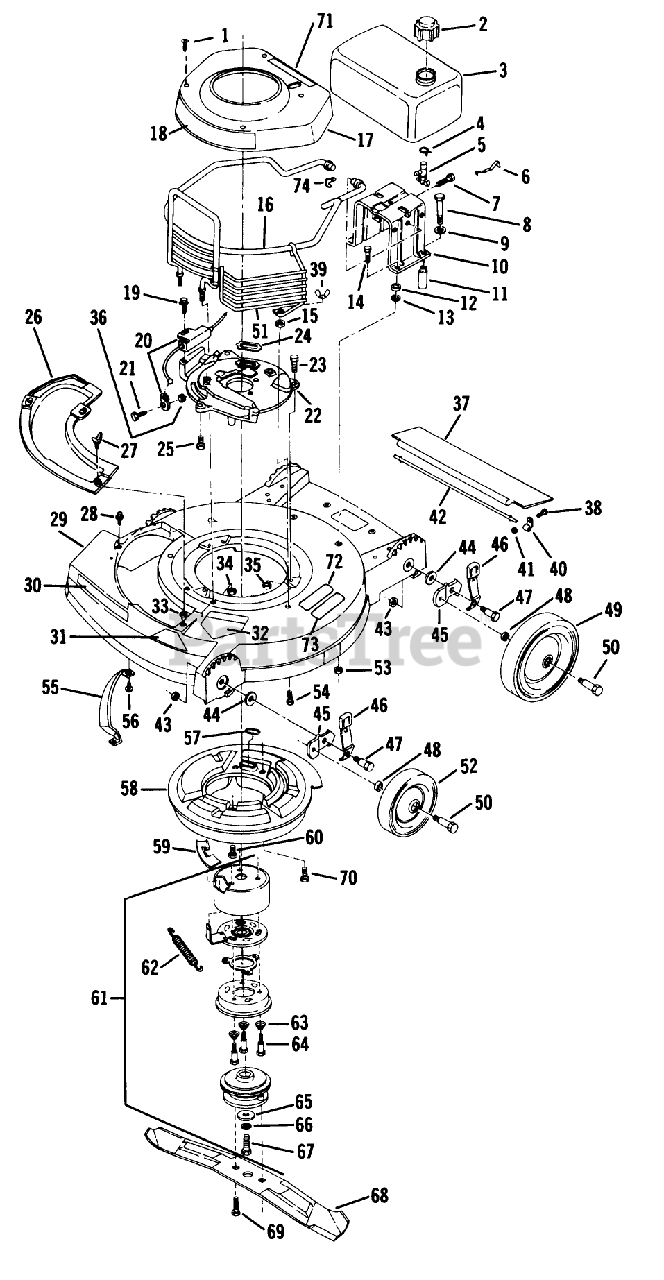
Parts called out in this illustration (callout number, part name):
1	SCREW - SELF TAPPING
2	FUEL CAP & INSERT
4	CLAMP - HOSE S
5	VALVE&SCREEN SM
7	SCREW S
14	BOLT PIONEER
15	LOCKNUT E
17	SHROUD S
25	SCREW V
27	WING SCREW LAWRE
34	NUT-LOCK F
35	NUT-LOCK F
36	LOCKNUT E
37	T/SHIELD GEAUGA
40	CLAMP ROD KMC
41	LOCKNUT E
42	ROD 21" ADVANCE
48	WASHER WROUGHT
49	WHL & TIRE AY
50	BOLT-SHOULDER
52	WHEEL & TIRE ASSY
53	LOCKNUT E
55	BAR-TOE
64	SCREW,SHOULDER SM
69	SCREW SEMS
73	PAD FOOT
